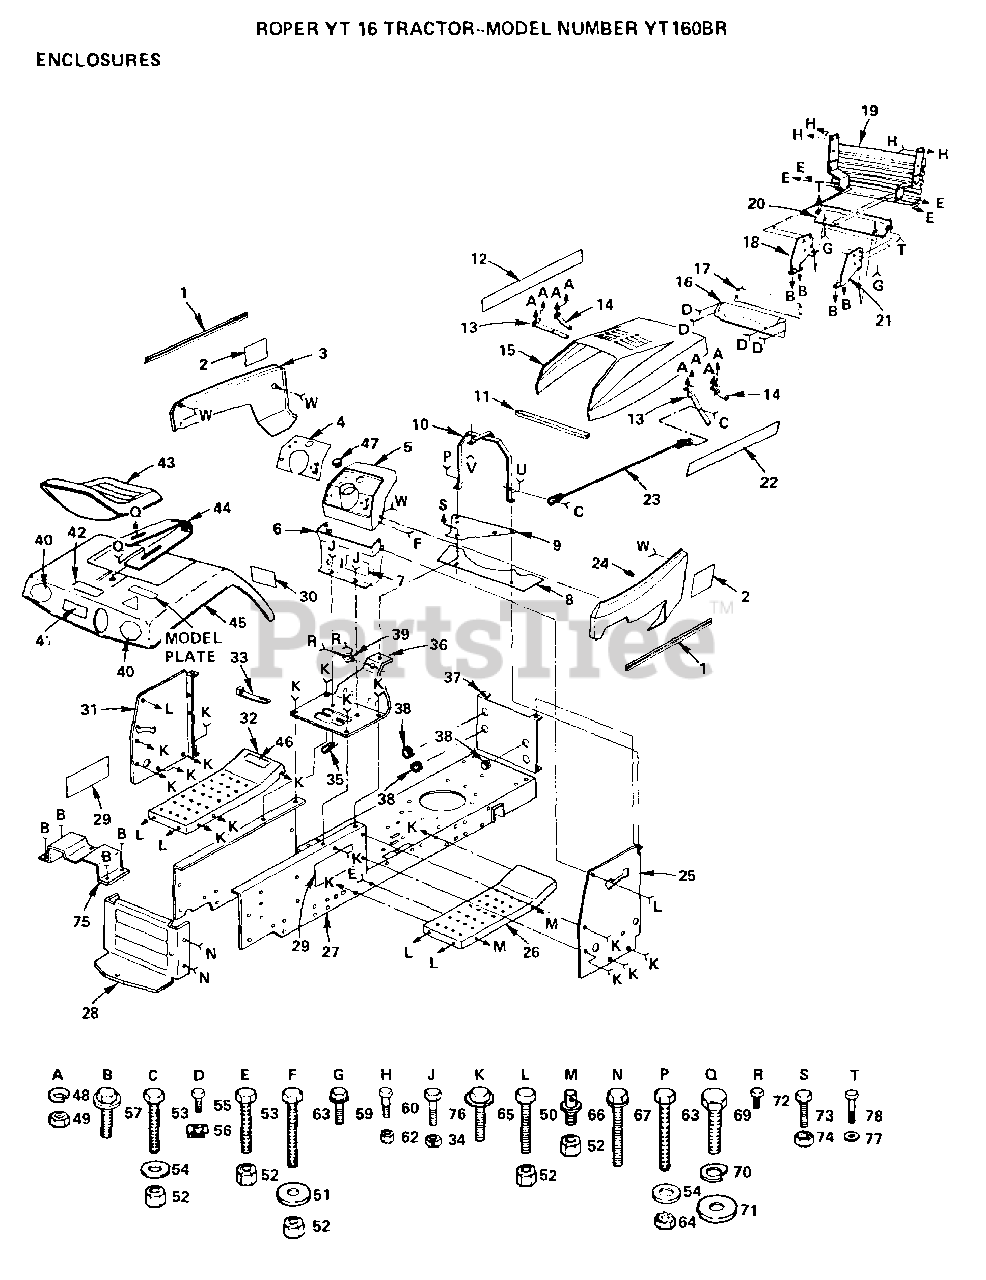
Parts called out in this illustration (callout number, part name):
6	LOWER DASH
7	DECAL, INSTRUCTION
9	PLATE, SUPPORT BATTERY
11	FOAM-STRIP LT
18	SUPPORT-GRILL LT
30	DECAL-CAUTION
33	WIRE TIE
35	CLIP T
38	SNAP BUSHING T
41	DECAL-CAUTION
47	PLUG-DASH T
51	WASHER
53	BOLT
54	WASHER
56	"""J"" FASTENER LT"
57	SCREW
59	SCREW
60	BOLT T
64	NUT
65	SCREW LT
66	PIN SUSPENS. LTV
67	SCREW GTV
69	BOLT
71	WASHER
73	BOLT
75	BRACKET ASSY - FENDER
77	WASHER PM
78	SCREW HEX CRT
